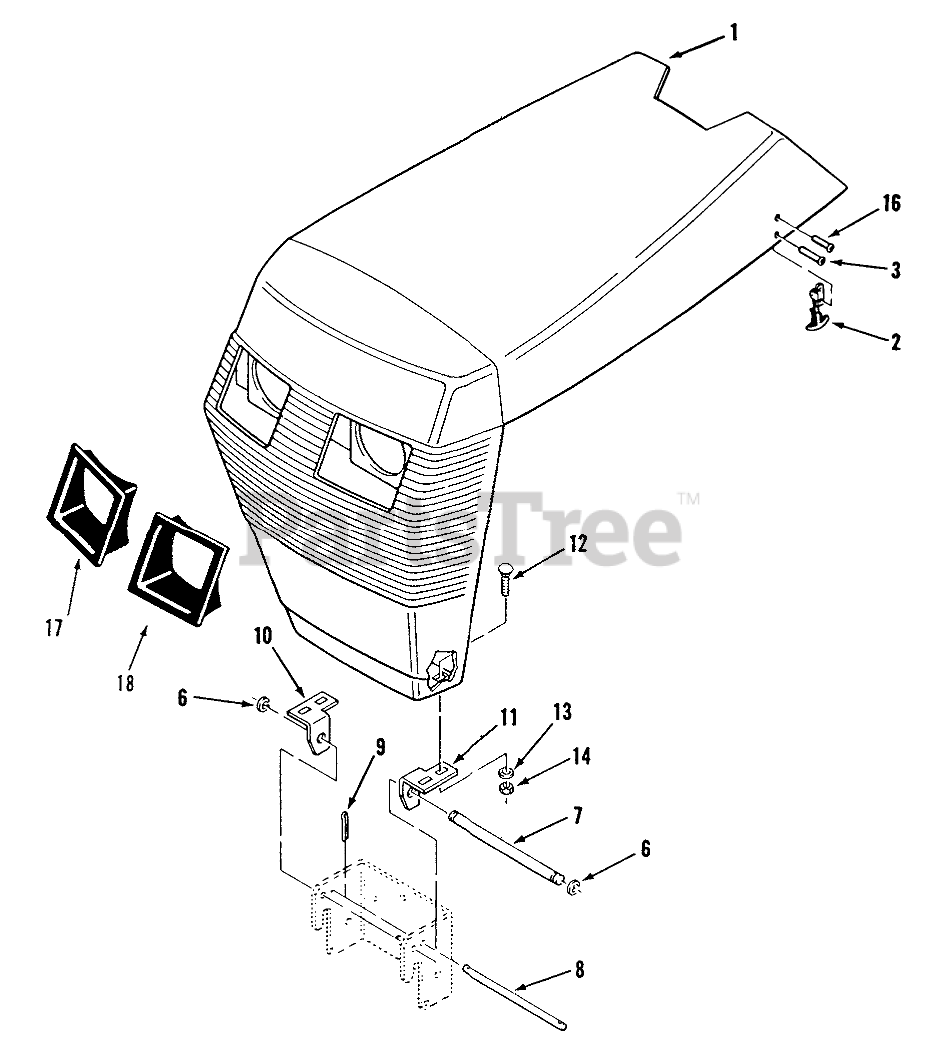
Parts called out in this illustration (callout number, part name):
1	Hood
2	Hood Latch (includes 109236 Handle Ass-y & 109237 Latch Keeper)
3	RIVET-POP
6	RING-RETAINING
7	ROD-GRILL PIVOT
8	ROD-HOOD STOP
9	Cotter Pin
10	BRACKET-GRILL, R H
11	BRACKET-GRILL, LH
12	Bolt-Carriage
14	Nut
16	RIVET
17	BEZEL-HEADLIGHT, RH
18	BEZEL-HEADLIGHT, LH
24	WASHER 5/16 SAE
